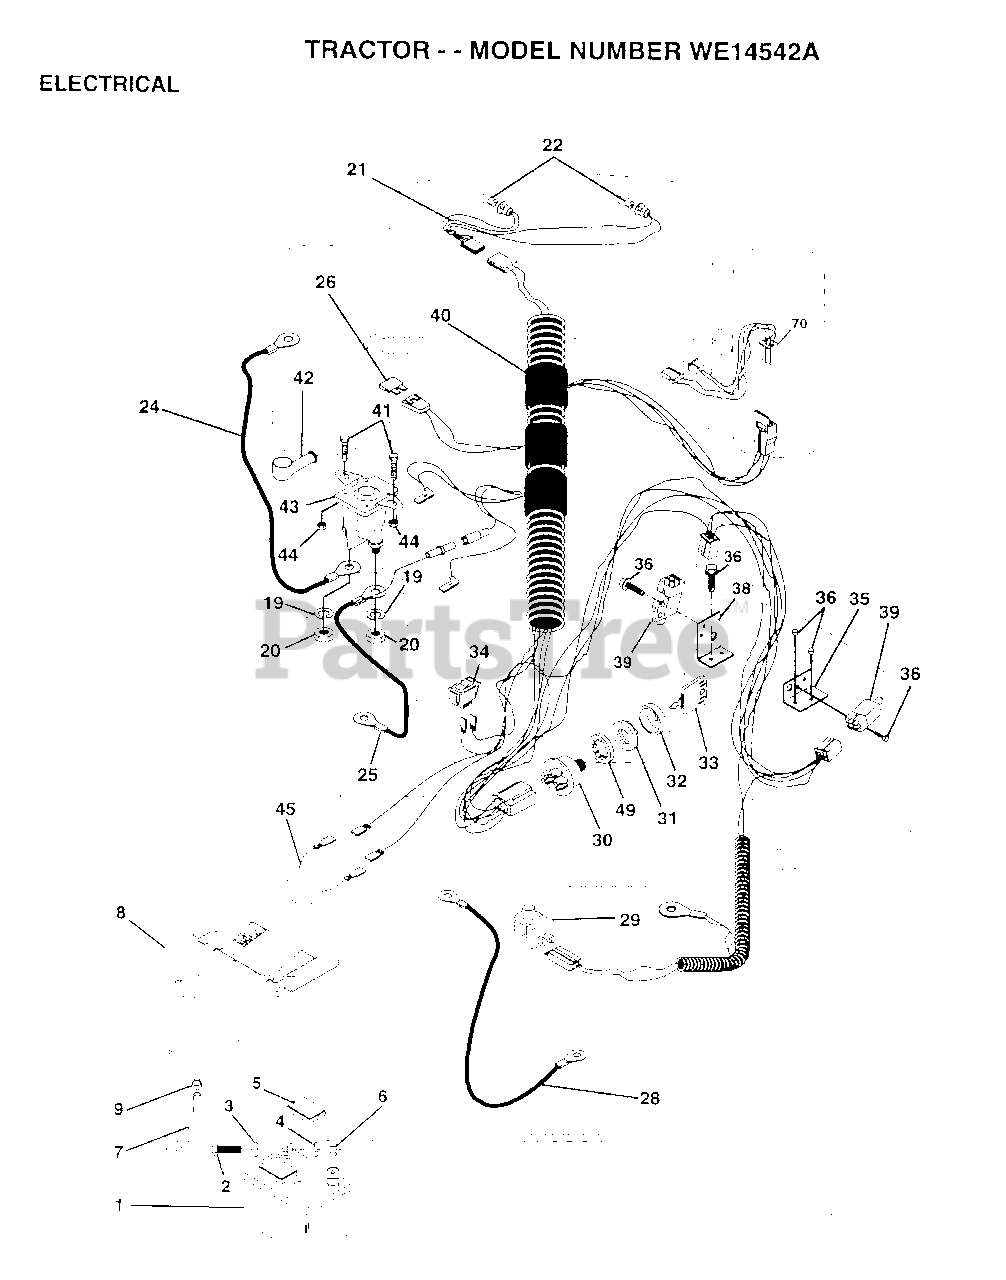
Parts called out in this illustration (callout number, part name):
2	BOLT LT
3	WASHER
4	LOCKWASHER
5	"CAP,BATTERY "
7	TUBE T
9	HOSE CLAMP T
20	NUT
21	"HARNESS,LIGHT SOC"
22	HEADLAMP BULB
24	"CABLE T, BATTERY"
25	CABLE.BTRY.6GA.RD
26	FUSE HYT
28	CABLE T
29	SWITCH SEAT
32	COVER KEY SWITCH
33	KEY MLD GEN DELTA
34	SWITCH LT
35	BRACKET LT
36	SCREW
38	BRACKET SWITCH IN
39	SWITCH INTERLOCKT
40	HARNESS.IGN.DASH.
41	BOLT.HX.1/4-20
44	NUT
45	ADAPTER AMMETER
49	LOCKWASHER
70	HARNESS.ENG.DUAL
